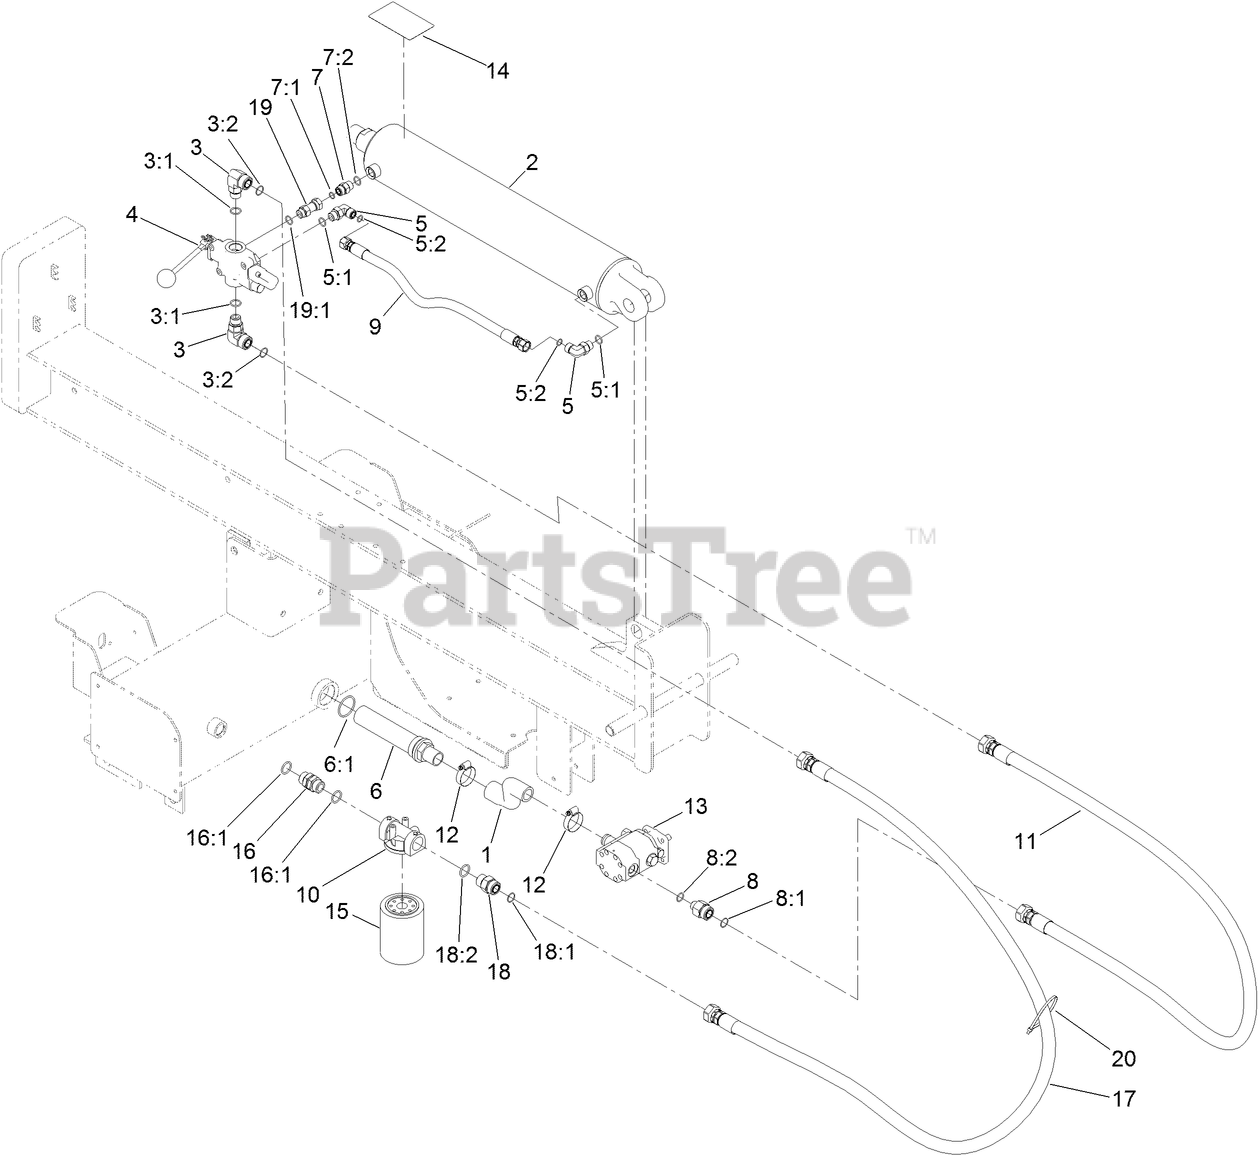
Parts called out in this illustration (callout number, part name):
1	HOSE-MOLDED
2	CYLINDER-HYD
3	FITTING-HYD, 90 DEG
3:1	O-RING
3:2	O-RING
4	VALVE-CONTROL
5	FITTING-ELBOW-90 DEG
5:1	O-RING
5:2	O-RING
6	STRAINER-TANK, OIL
6:1	O-RING
7	FITTING-STRAIGHT
7:1	O-RING
7:2	O-RING
8	FITTING-STR
8:1	O-RING
8:2	O-RING
9	HOSE-HYD
10	HEAD-FILTER
11	HYD HOSE ASM
13	PUMP-HYD
14	DECAL- CAUTION, CONTROL
15	FILTER-OIL, TRANSMISSION
16	FITTING-THREAD, STRAIGHT
16:1	O-RING
17	HYD HOSE ASM
18	FITTING-STR
18:1	O-RING
18:2	O-RING
19	ADAPTER-HYD
19:1	O-RING
20	TIE-CABLE
